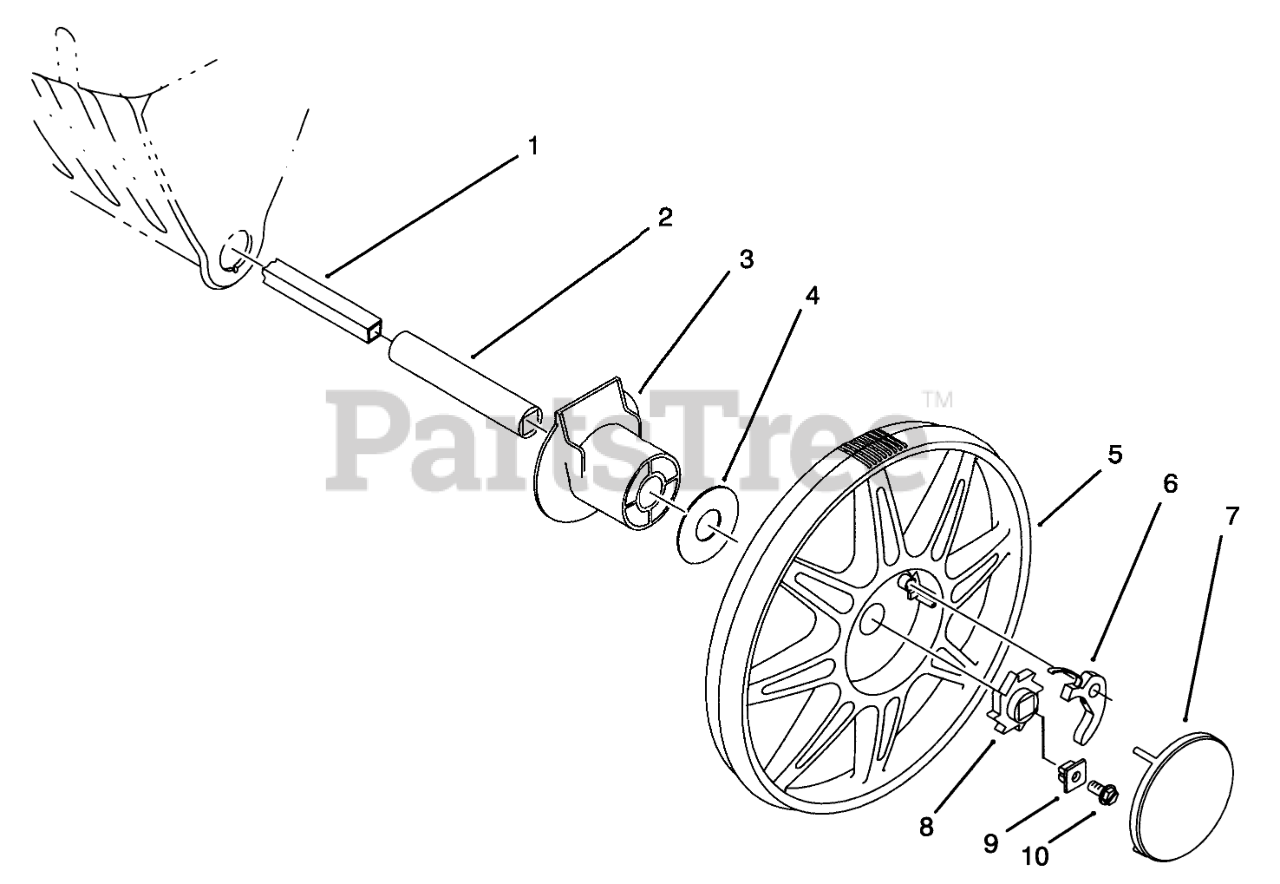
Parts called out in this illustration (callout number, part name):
2	BUSHING - AXLE
3	Support-Axle
4	WASHER-THRUST
5	Tire & Wheel Assembly
6	Pawl-Wheel Clutch
7	Cap-Wheel
8	Gear-Wheel Clutch, R.H.
9	Gear-Wheel Clutch, L.H.
9	RETAINER - AXLE
10	SCREW
